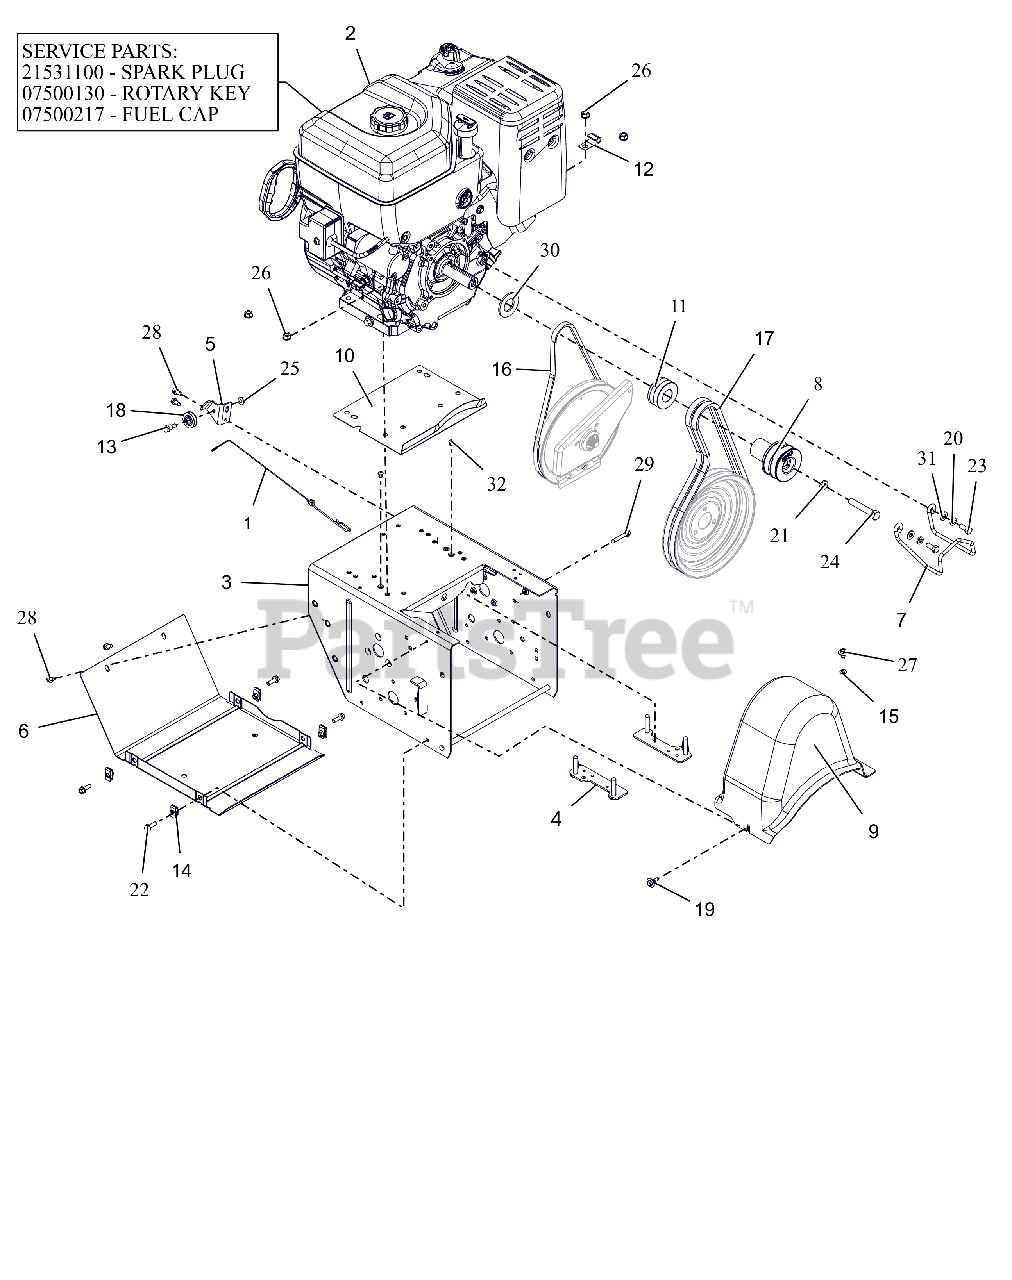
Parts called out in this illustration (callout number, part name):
1	CABLE, LOWER TRACTION,SS & PRO
2	ENGINE, BRIGGS PF 2100, 120V
2	PLUG, SPARK 20HP B&S VANGUARD
2	KEY, IGNITION ROTARY B&S
2	CAP, FUEL - BRIGGS & STRATTON
3	FRAME, MAIN - PRO (WELDMENT)
4	STRAP, BOLT-LARGE
5	BRACKET, CABLE PULLEY
6	COVER, BOTTOM
7	FINGER, BELT
8	SHEAVE,ATTACHMENT-SHO 2 GRV
9	COVER, BELT-LARGE
10	BAFFLE, WATER - LARGE BLOCK
11	SHEAVE, TRACTION (KEYLESS)
12	J-CLAMP
13	BOLT, SHLDR -.375 X .375 X .25-20
14	NUT-RTNR .25-20X.56
15	NUT-PUSH .25X.50 O.D.
16	V-BELT, 3L-WRAPPED
17	V-BELT, HA-RAW EDGE (SET)
18	PULLEY, CABLE
19	SCR-TAP .25-20X.5 CAPTIVE
20	WSHR, LK-HVY .312X.097 ZCC
21	WSHR, LK-REG .438X.109 ZCC
22	BLT, HWH .25-20X.75 G5 ZCC
23	BLT, HEX .31-24X.750 G5 ZCC
24	BLT, HEX .44-20X2.50 G5 ZCC
25	NUT-LK-TOP-FLG .250-20 GF ZCC
26	NUT,LK-CTR-FLG .31-18 GF ZCC
27	SCR, TAP .25-20X.50 LG HWH ZCC
28	SCR-TAP .25-20X.50 HWH ZCC
29	SCR,TAP .25-20X1.50 HWH TR ZCC
30	WSHR, FLT 1.062X2.000X.134 ZCC
31	WSHR,FLT .344X.688X.065 ZCC
32	RVT, POP .1875 ZCC
